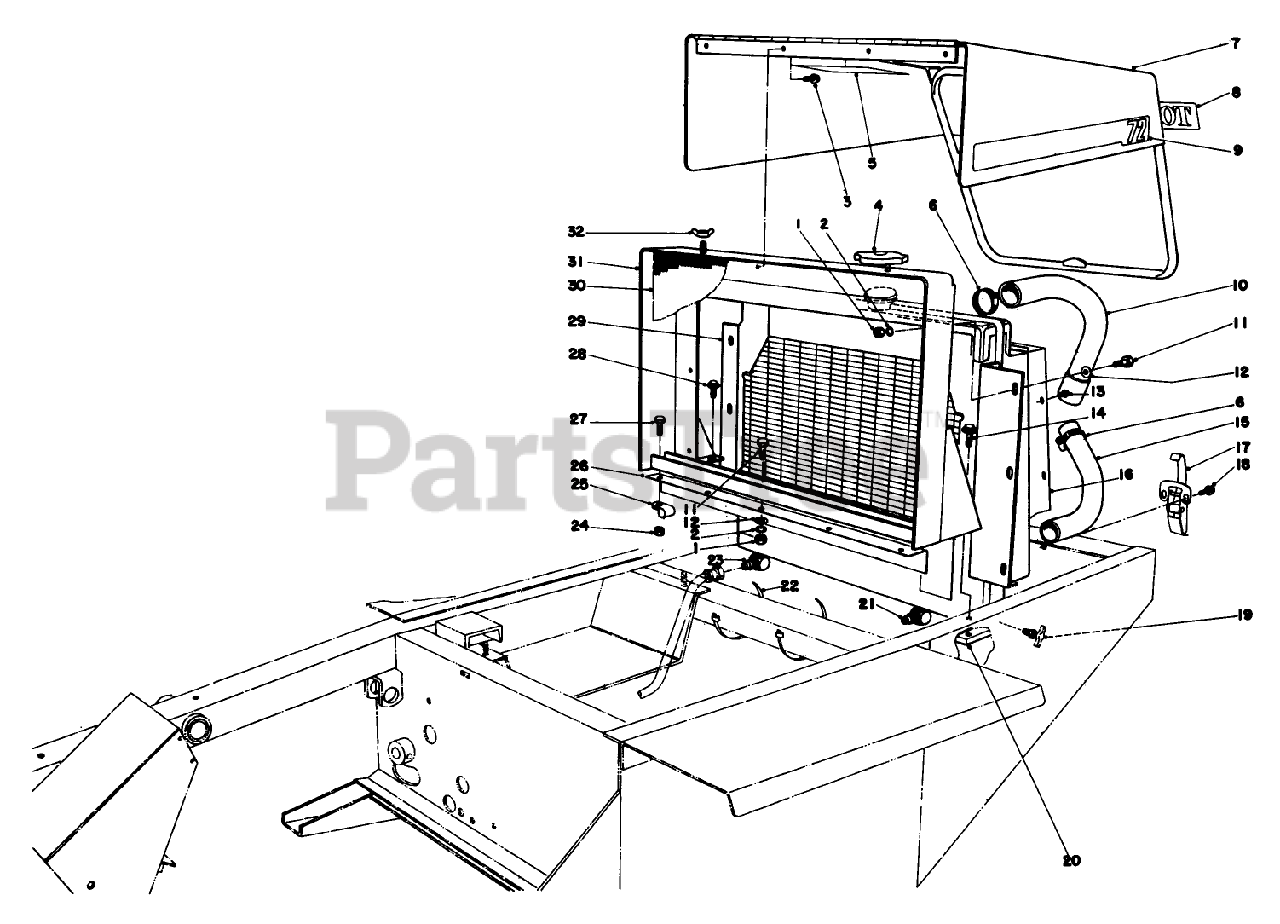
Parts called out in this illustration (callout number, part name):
1	NUT-HEX
2	WASHER-LOCK
3	SCREW-HWH
4	RAD PRESS CAP ASM
5	Decal
6	CLAMP-HOSE
7	Hood
8	Decal
9	DECAL
10	UPPER HOSE
11	SCREW-HH
12	WASHER-PLAIN
13	SCREW-THD FRM,HWH
14	SCREW-HHF
15	LOWER HOSE
16	Radiator Shroud
17	CLAMP-SLOTTED
18	10-24 X 1/2 SEMS SCR
19	DRAINCOCK
20	LH FRAME BAR
21	ELBOW
22	TIE-CABLE
23	ELBOW
24	NUT-HF
25	CLAMP-R
26	Sealing Plate Grill
27	SCREW-HH
28	SCREW-HWHTF
29	RADIATOR ASM
30	GRILLE WA R
31	Radiator Support
32	NUT-WING
